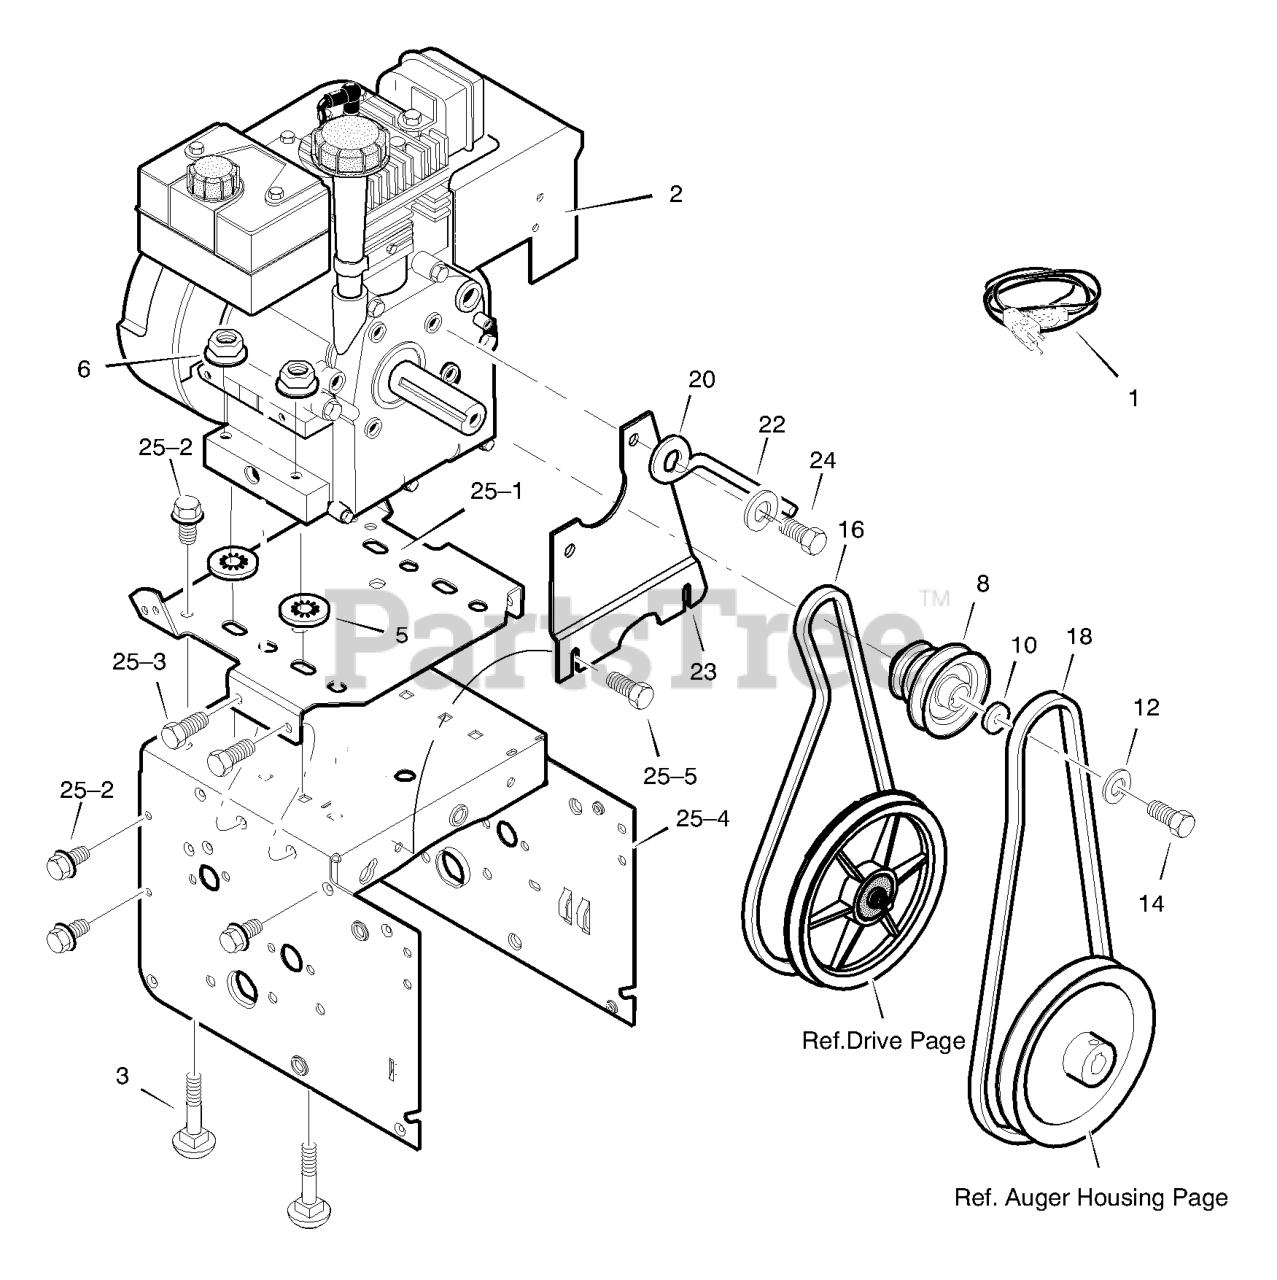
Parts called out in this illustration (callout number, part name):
1	CORD, Electric, 10FT. 110V
2	ENGINE
3	BOLT, CARRIAGE 5/16-18
5	RETAINER, PUSH
6	NUT, HEX 5/16-18
8	PULLEY, ENGINE
10	WASHER
12	WASHER .38ID
14	SCREW, 3/8-24 x 1.00
16	BELT, V 3L 33.13LG
18	BELT, V 4L 38.1MF16" 5-10
20	GUIDE, BELT
22	WASHER, SPTLK .31X.58X.08
23	PLATE, ANTI VIBRATION
24	SCREW, 5/16-24 X 1.00
25	FRAME ASSEMBLY
25-1	PLATE, ENGINE MOUNT
25-2	SCREW, TAP 1/4-20 X .63
25-3	SCREW, TAP 5/16-18 X .50
25-4	FRAME, MOTOR BOX
